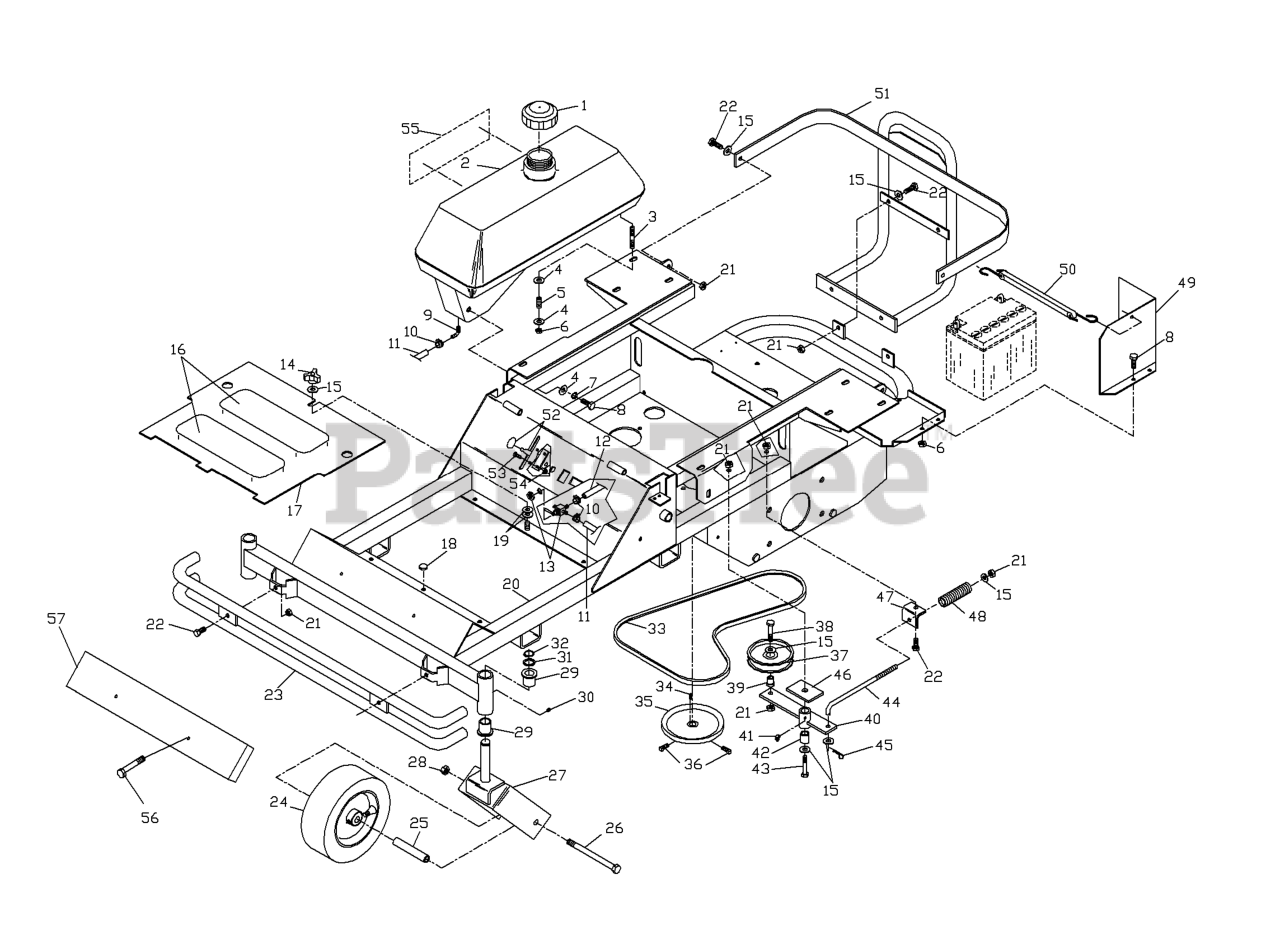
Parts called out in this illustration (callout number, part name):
1	FUEL CAP
2	FUEL TANK RT
3	STUD, 5/16C
4	WASHER 5/16 FLAT
6	NUT 5/16C CENTERLOCK
7	WASHER.LOCK.HVY.HLCL.SPR.5/16
8	HCS 5/16C X 3/4
9	HOSE BARB 90 DEGREE
10	HOSE CLAMP
11	FUEL LINE 21.5" TANK
12	FUEL LINE, ENGINE
13	FUEL VALVE
14	KNOB, THREE PRONG
15	WASHER 3/8 FLAT
16	ANTI-SKID PAD
17	FOOTPLATE
18	GROMMET, BUMPER
19	WASHER, 3/8 DISC SPRING SPEC
20	FRAME W/DECALS KAWASAKI
20	FRAME W/DECALS KOHLER
21	NUT 3/8C CENTERBLOCK
22	HCS 3/8-16X1.GRD.5.ZD
23	BUMPER, FRONT
24	TIRE, CASTER (COMPLETE)
24	TIRE/WHEEL.CASTER
24	TIRE.11X4.00-5NHS.4PR.SMOOTH
24	TIRE - CASTER
24	ROLLER BEARING-CAGED 3 1/4'
24	ZERK
24	BEARING RETAINER
26	HCS 1/2C X 5 1/2
27	YOKE WELDMENT ORANGE
28	NUT 1/2-13 HEX NYLOC ZD
29	BUSHING, FLANGED
30	ZERK
31	BSHG .875 X 1.375 X .074 ZD
32	RETAINING RING, 7/8"
34	KEY 5 MM SQ X 25 MM
36	SCREW 5/16C X 5/8 SQ HEAD
37	IDLER PULLEY
38	HCS 3/8-16 X 1 3/4 GR5
39	BUSHING, IDLER FLANGE
40	IDLER ARM WELDMENT
41	ZERK
42	PIVOT BUSHING
43	HCS 3/8C X 3
44	TENSION ROD
45	RP_COTTER PIN 1/8 X 3/4
46	SUPPORT PLATE
47	TENSION BRACKET
48	COMPRESSION SPRING
49	BATTERY GUARD W/DECA
50	BATTERY STRAP
51	ENGINE GUARD W/DECAL
52	THROTTLE CABLE
53	HCS #10-24 X 1/2
54	NUT 10-24 NYLOC
55	DECAL, ZTH4218
55	DECAL ZTH4221
55	DECAL, ZTH4818
55	DECAL ZTH4820
55	DECAL, ZTH4821
56	HCS 3/8C X 2 1/4
57	WEIGHT BLOCK
58	CHOKE CONTROL, COMPLETE
